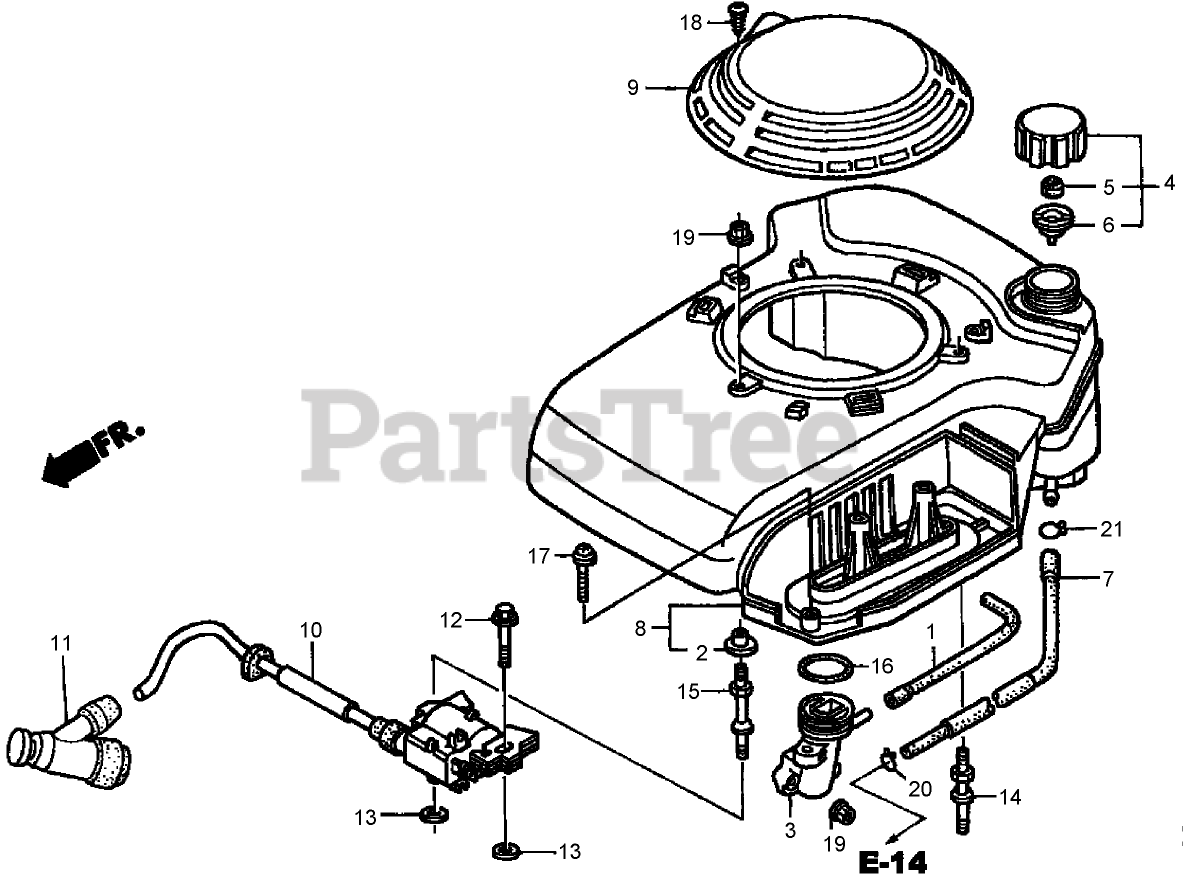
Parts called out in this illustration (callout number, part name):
1	Tube-Breather
2	COLLAR-CLEANER, AIR
3	ELBOW-CLEANER, AIR
4	FUEL TANK CAP ASM
5	Sponge-BREATHER, Fuel Cap
6	GASKET-CAP, FUEL
7	FUEL TANK TUBE ASM
8	COVER-FAN
9	HOOD-COVER, FAN
10	IGNITION COIL ASM
11	NOISE SUPPRESSOR CAP ASM
12	BOLT-FLANGE (6X28) (C T200) (engine serial numbers starting at 6901761)
13	WASHER-PLAIN (6MM)
14	BOLT A-STUD
15	BOLT-STUD
16	O-Ring (33.3X3.5)
17	SCREW-WASHER (6X35)
18	Screw-Tapping (4X20)
19	NUT-FLANGE (6 mm)
20	CLIP-TUBE (B8)
21	CLIP-TUBE (C9)
